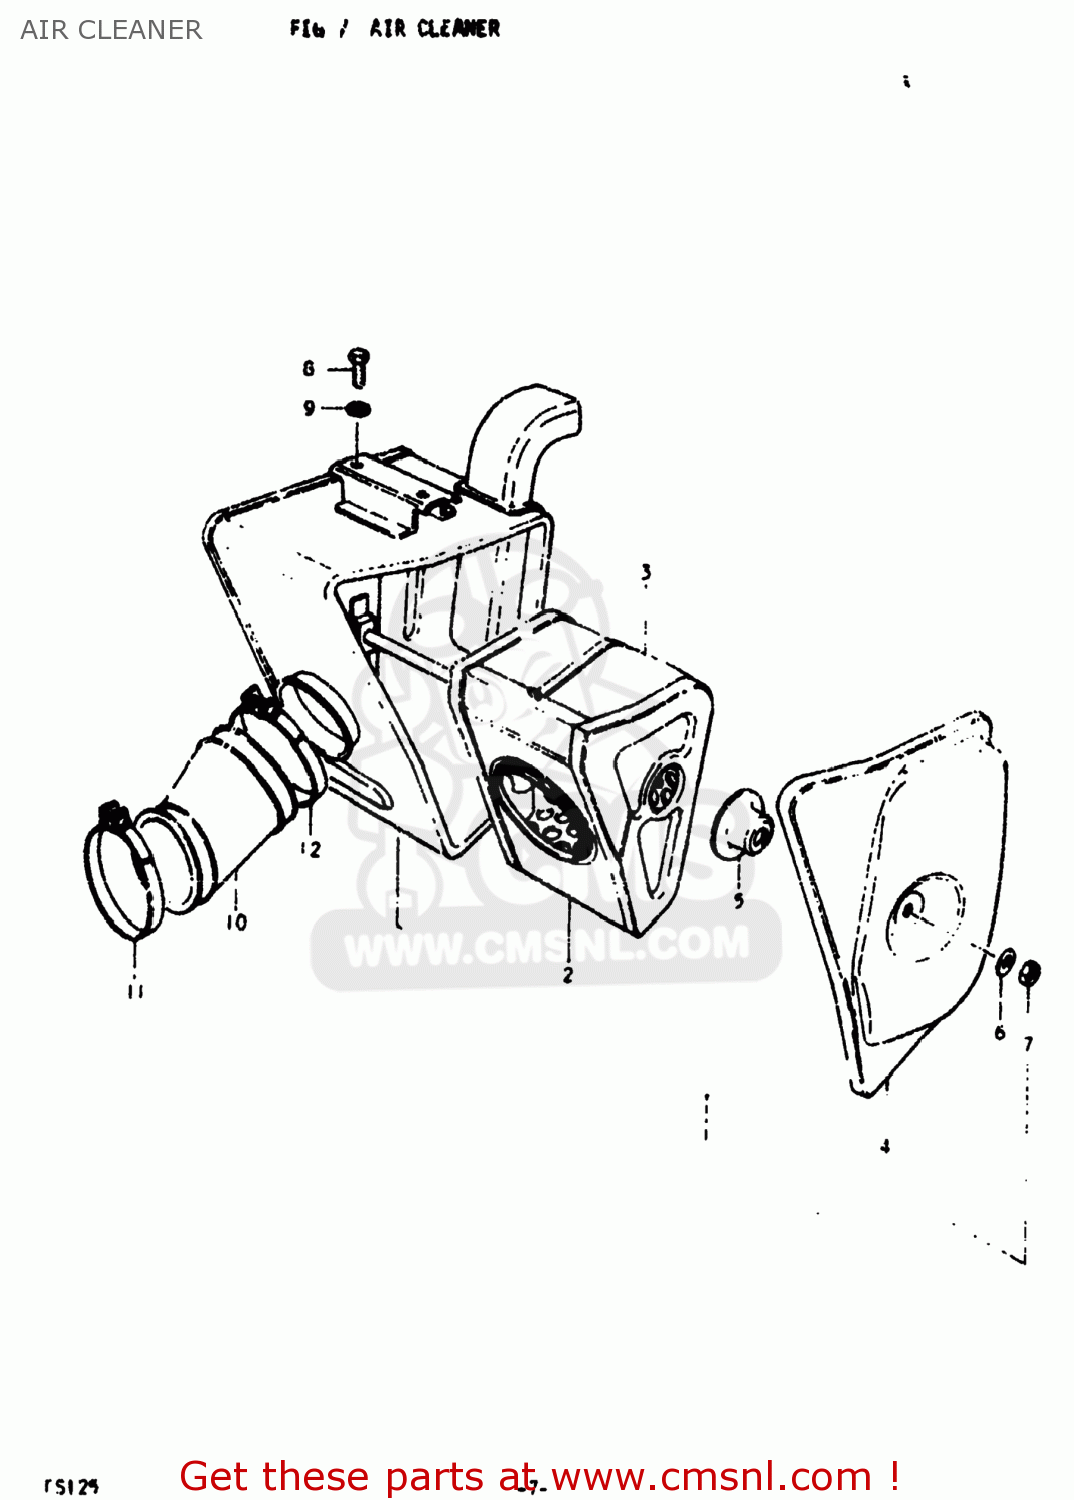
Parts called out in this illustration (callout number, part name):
1	CLEANER ASSEMBLY,AIR
2	FILTER ASSY,AIR CLEANER
3	FILTER
4	CAP
5	SPACER
6	WASHER
7	NUT
8	BOLT
9	WASHER
10	HOSE,CARBURETOR AIR INLET
11	CLAMP
12	CLAMP
